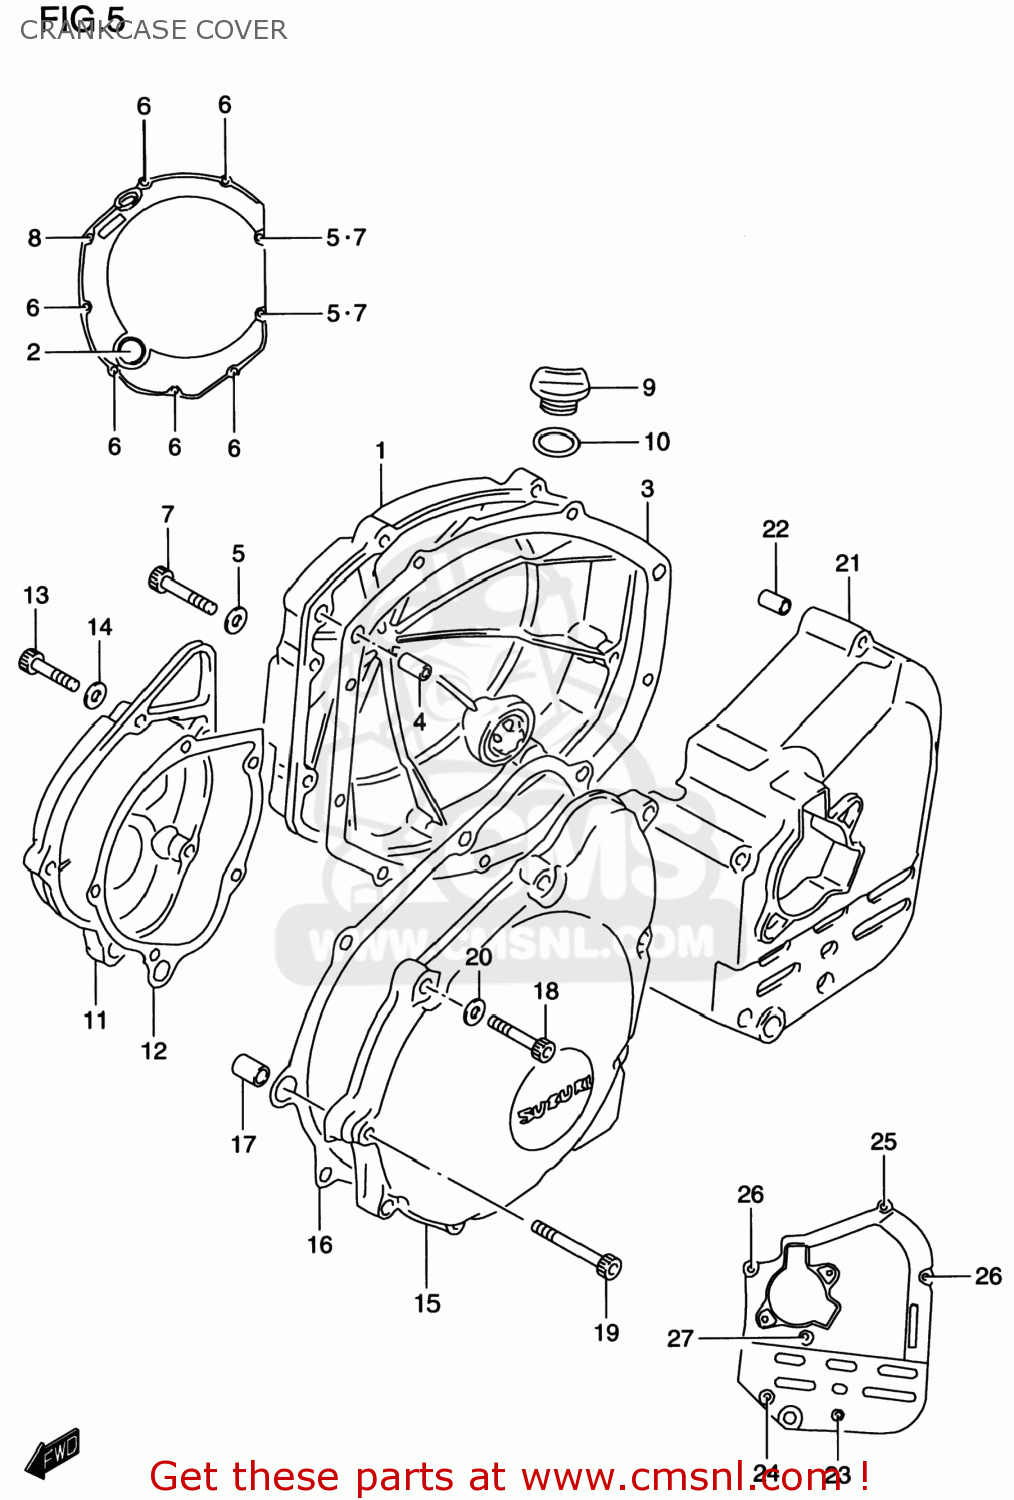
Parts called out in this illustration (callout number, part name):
1	COVER,CLUTCH
2	LENS,OIL LEVEL CHECK
3	GASKET,CL COVER (NAS)
4	PIN
5	GASKET(5.8X11X1.2) (NAS)
6	BOLT,CL.COVER
7	BOLT
8	BOLT
9	PLUG
10	O RING(D:3.1,ID:16.8)
11	COVER,SIGNAL GENERATOR
12	GASKET,SIGNAL GEN COVER (NAS)
13	BOLT(6X22)
14	GASKET(5.8X11X1.2) (NAS)
15	COVER,STARTER GEAR
16	GASKET,STARTER GEAR COVER (NAS)
17	PIN(8.4X11X20)
18	BOLT,CL.COVER
19	BOLT
20	GASKET(5.8X11X1.2) (NAS)
21	COVER,ENGINE SPROCKET
22	PIN
23	BOLT
24	BOLT
25	BOLT
26	BOLT
27	BOLT
